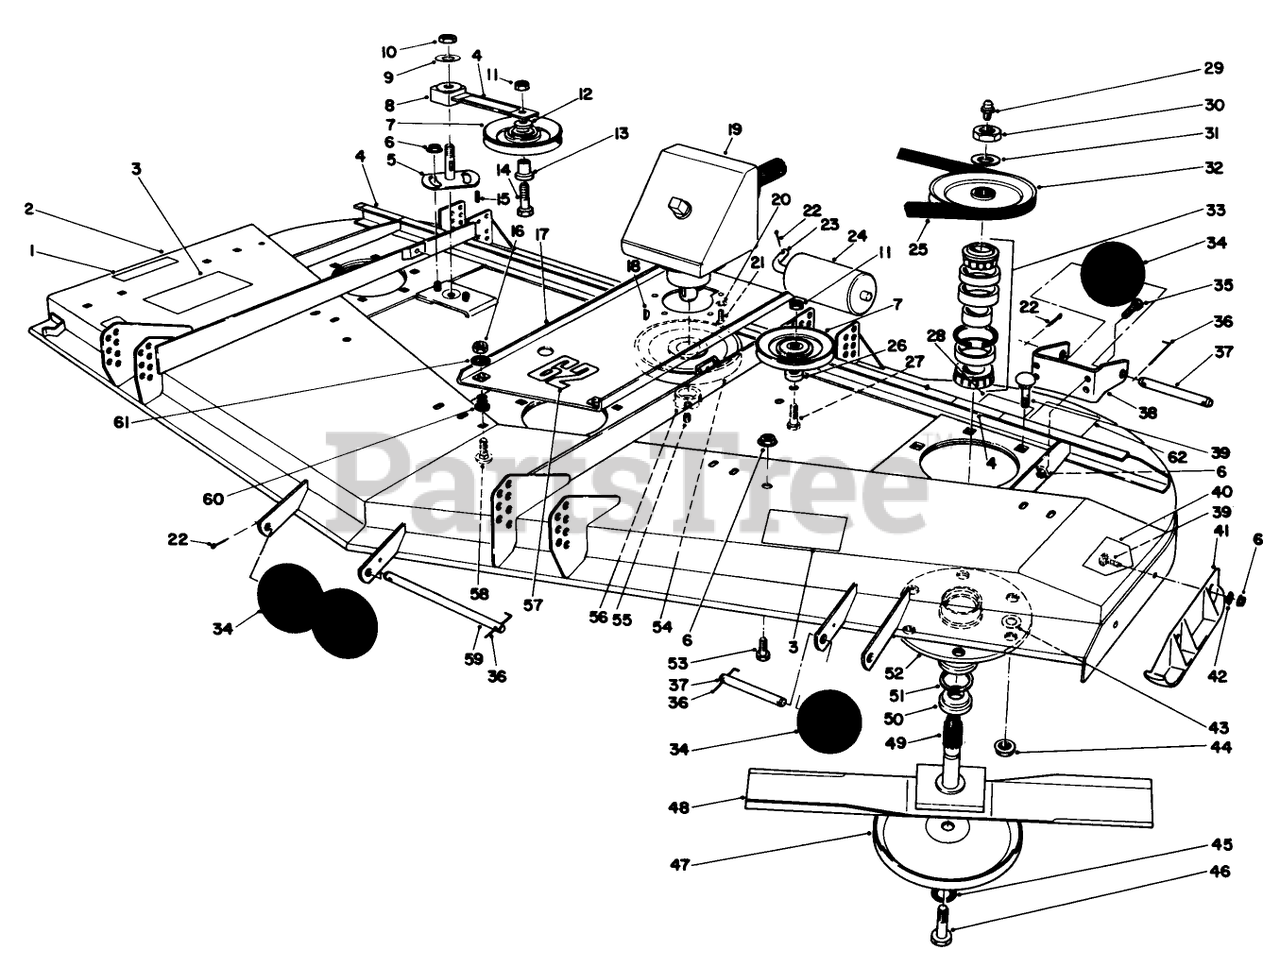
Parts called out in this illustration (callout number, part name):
1	DECAL-DANGER
2	Cutting Deck
3	DECAL-DANGER, THROWN OBJECT
4	DECAL-DANGER
5	PLATE-IDLER
6	NUT-HHF, WHIZ
7	PULLEY-IDLER
8	IDLER ARM ASM
9	WASHER-FLAT
10	NUT-LOCK, NI
11	NUT-HEX
12	WASHER-FLAT
13	BUSHING-PULLEY
14	SCREW-HH
15	KEY-SQUARE
16	NUT-LOCK, SIDE
17	GEARBOX BASE WA R
18	KEY-WOODRUFF
19	GEAR BOX ASM
20	WASHER-LOCK
21	SCREW-HSH
22	PIN-COTTER
23	SHAFT-ROLLER, REAR
24	ROLLER-DECK
25	V-BELT
26	SPACER
27	SCREW-HH
28	DECAL-TORQUE
29	FITTING-GREASE
30	NUT-HEX
31	WASHER
32	PULLEY AND HUB ASM
33	BEARING ASM
34	ROLLER
35	SCREW-HH
36	PIN-SPECIAL
37	SHAFT-ROLLER
38	Bracket-Roller
39	SCREW-CARR
40	DECAL-DANGER
41	Skid
42	LOCKWASHER-PYRAMID
43	WASHER-FLAT
44	NUT-HF
45	WASHER-LOCK
46	SCREW-BLADE
47	Cup-Scalp
48	Blade
49	SHAFT
50	SPACER
51	SEAL-OIL
52	HOUSING-SPINDLE
53	SCREW-HH
54	PULLEY
55	SCREW-SET, HSH
56	Bushing, Taper Lock (Incl. Ref. #55)
57	DECAL
58	SCREW-CARR
59	SHAFT-ROLLER
60	MOUNT
61	WASHER
62	DECAL-WARNING
